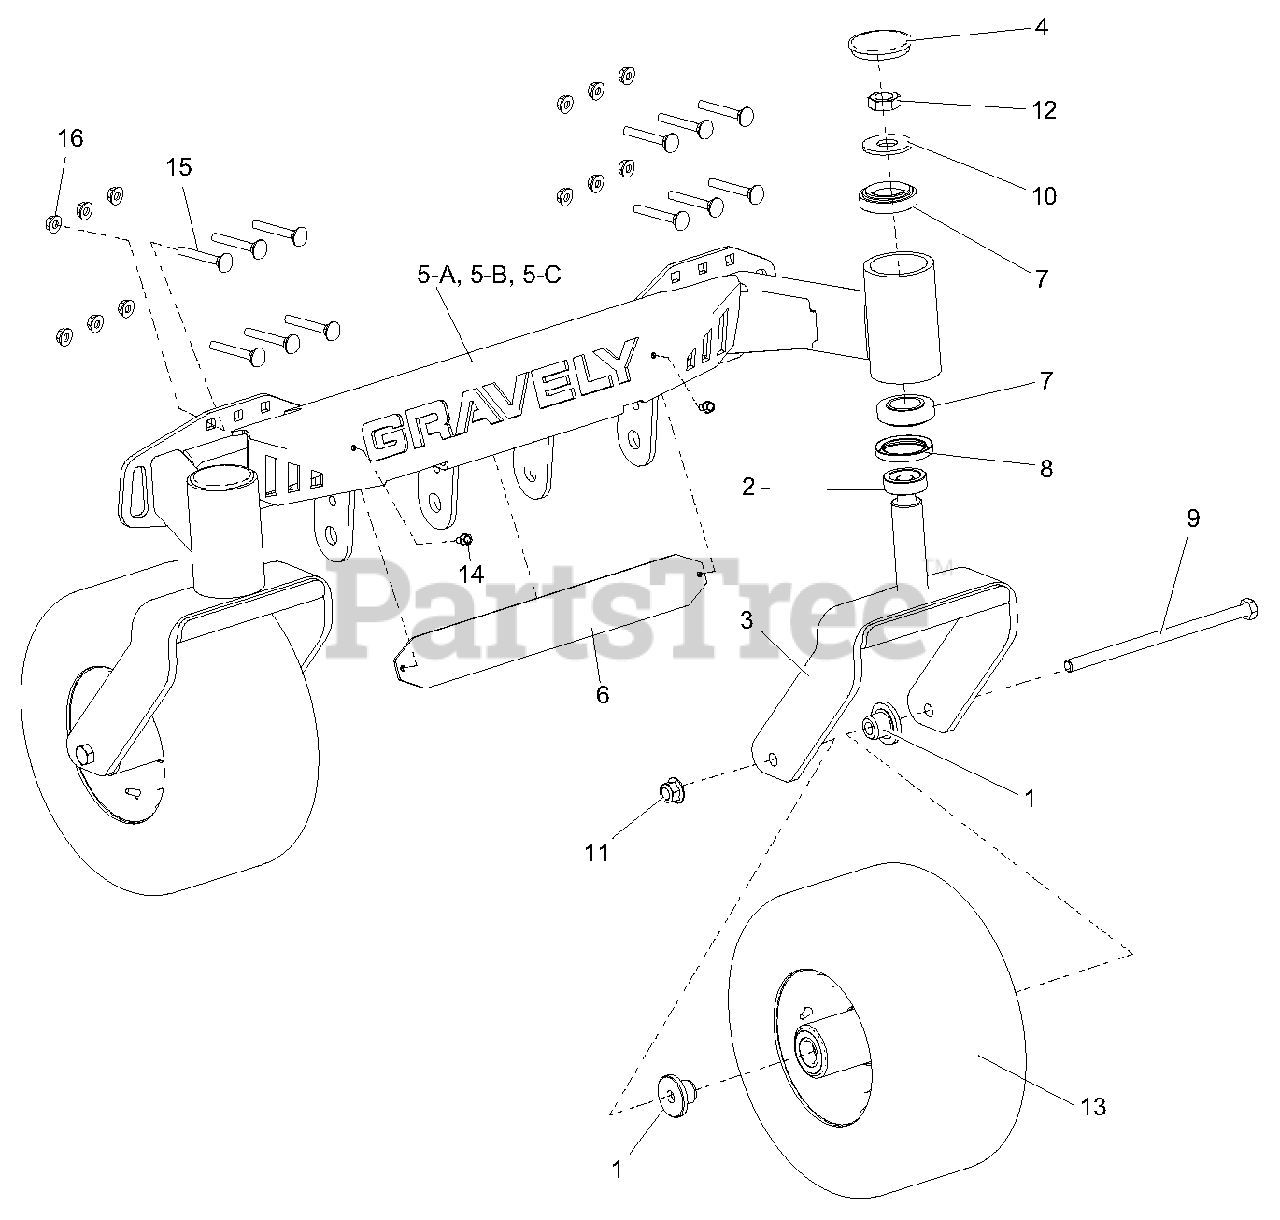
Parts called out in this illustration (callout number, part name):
1	SPACER, FRONT WHEEL
2	SPACER 1.258 ID X 1.750 OD .550
3	WMT, CASTER FORK
4	CAP, DUST
5A	WLDMT, 48 FRONT AXLE (994111,117)
5B	WLDMT, 52 FRONT AXLE (994112,113,118)
5C	WLDMT, 61 FRONT AXLE (994114,115)
6	PLATE, BACK NAME
7	BEARING CUP 2.328 X .465
8	SEAL, OIL 1.75 X 2.332 X .312
9	BLT HEX .50-13 X 9.00 GR5 YWZC
10	WSHR-FL-STL .812 X 2.00 X .148 YWZC
11	NUT LK NYL FLG .50-13 YWZC
12	NUT JAM CENTER LOCK .75-16
13	TIRE/WHEEL, ASM 13 X 6.50
14	SCR-TAP .25-20 X .50 HWH TR YWZ
15	BLT RDHDSQNK .38-16 X 1.25 G5YZ
16	NUT LK TOP FLG .38-16 YWZC
